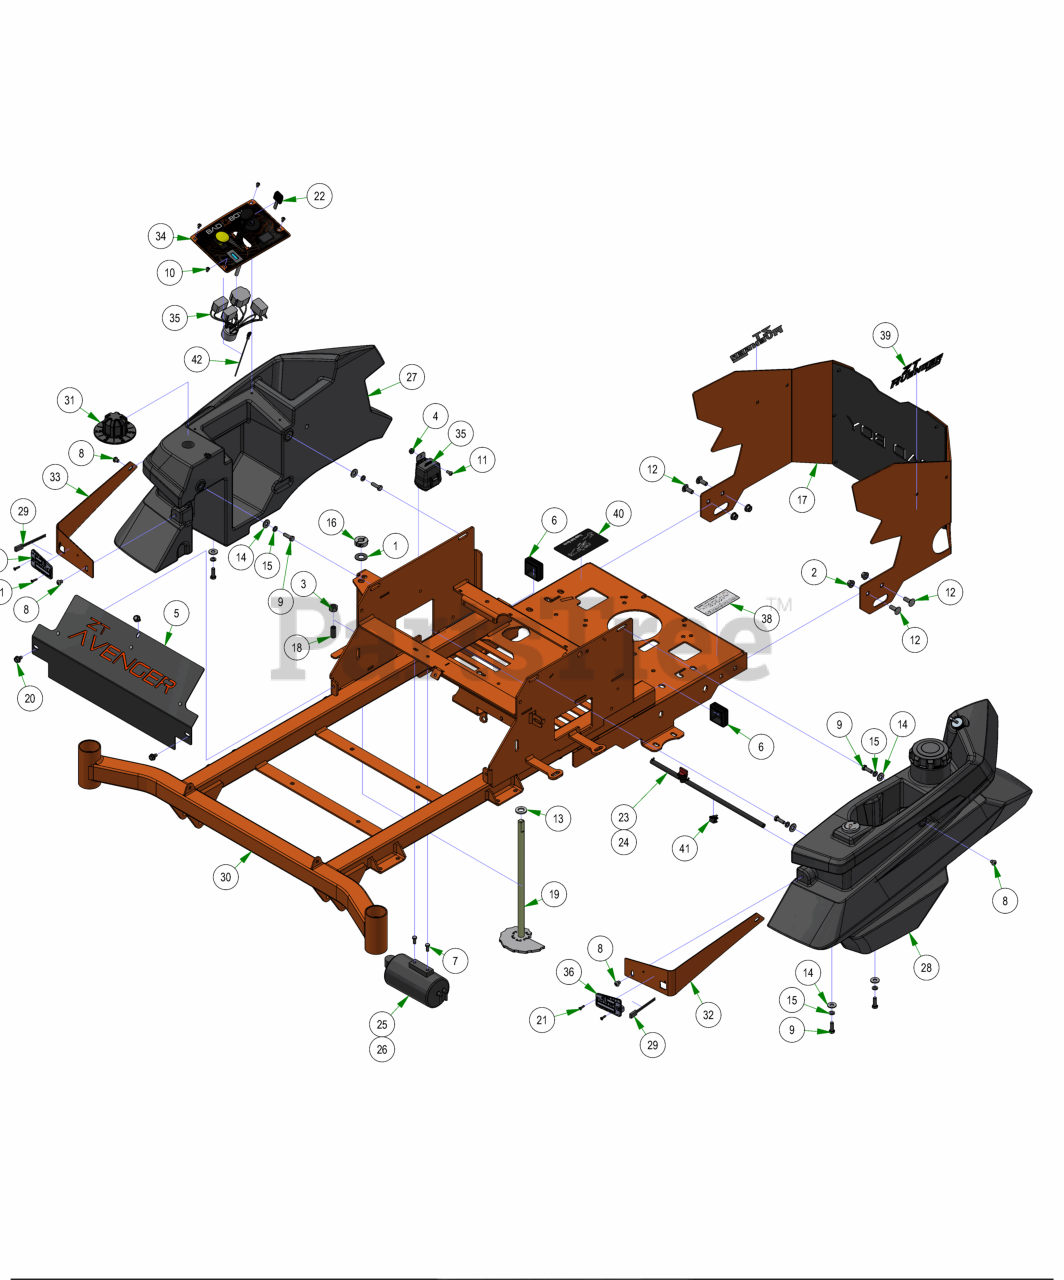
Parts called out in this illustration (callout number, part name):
1	.625 ID x 1.250 OD x .062 THK F/W Nylon
2	3/8-16 NYLON INSERT FLANGE LOCKNUT (GR.F) ZINC
3	1/2-13 HEX NUT ZINC
4	1/4-20 HEX SERRATED FLANGE NUT HARD/ZINC
5	2023 ZT Avenger Cooler Cover Assembly
6	2X2 Frame Plug
7	M6-1.0 X 16MM DIN 933 HEX TAP BOLT (CL 8.8) ZINC
8	5/16-18 x 3/8 Button SOC CAP BLACK
9	5/16-18 X 1 HEX CAP SCREW (GR.5) ZINC
10	10-32 X 3/8 BUTTON SOCKET CAP SCREW 18-8 STAINLESS STEEL
11	1/4-20 X 1/2 BUTTON SOCKET CAP SCREW 18-8 STAINLESS STEEL
12	3/8-16 X 1 CARRIAGE BOLT (GR.5) ZINC
13	.635 ID X 1.120 OD X .140 THICK FLAT WASHER NYLON
14	5/16 USS FLAT WASHER (7/8 OD) ZINC
15	5/16 SPLIT LOCKWASHER ZINC
16	5/8" Split Collar
17	2025 Avenger Rear Cover Assembly
18	Dial Rod Plunger
19	ZT Deck Height Bar Assembly
20	5/16-18 X 1/2 HWH unslot (F) tcs zinc
21	Domed Head Blind Rivets, 5/32" Diameter
22	Ignition Key
23	15" Fuel Line Assembly
24	31" Fuel Line Assembly
25	ZT/Mav EPA Cannister Assy
26	Avenger Kohler EPA Cannister Assy
27	2025 Aven, Magnum & Rambler RH Consol Tank
28	2025 Aven, Magnum & Rambler LH Fuel Tank
29	Pigtail For Tank Lights
30	2025 MZ-Avenger 54-60 Frame
31	MZ/ZT Deck Height Dial
32	2025 Avenger Metal tank insert - Right
33	2025 Avenger Metal tank insert -left
34	2025 Small Mower Control Panel Assembly
35	2025 Wiring Harness with Clips and Lights
36	LH Tank Light
37	RH Tank Light
38	2025 EPA Build Date Punch Decal
39	Avenger Back Plate Decal
40	Pump Belt Route Decal-Pump Plate
41	Edge Clip With Ziptie
42	2017 MZ/ZT/MAV Tach Wire Assy
